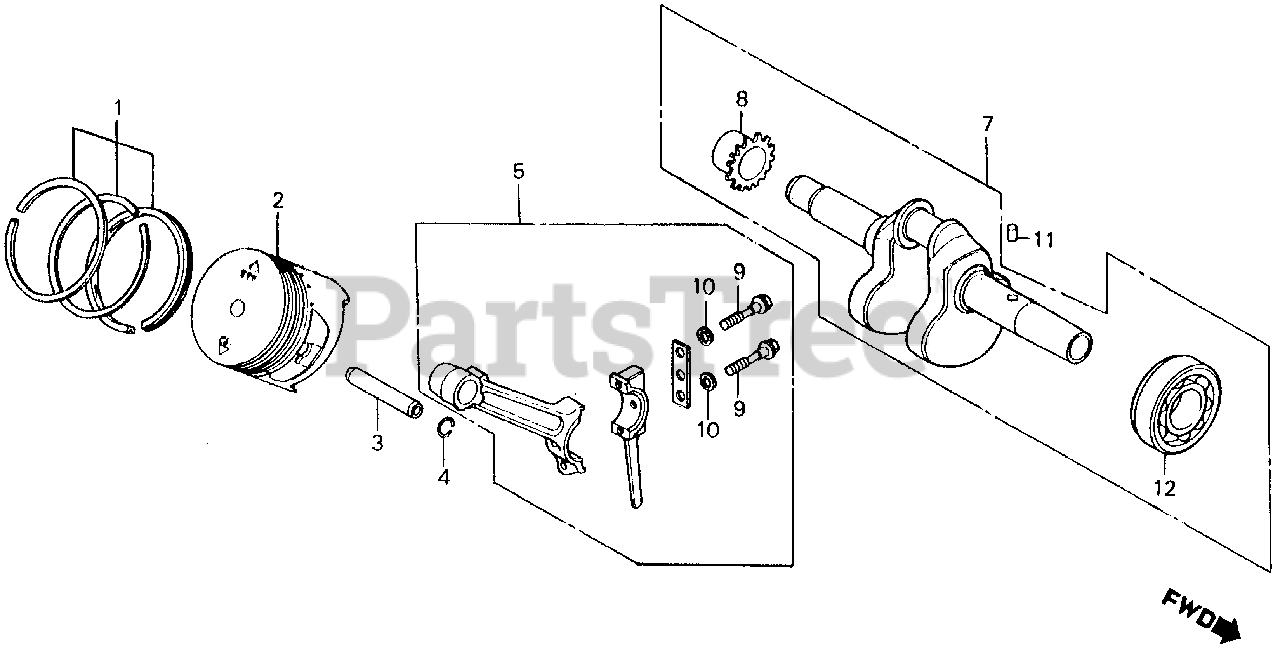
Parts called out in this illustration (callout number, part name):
1	RING SET, PISTON (STD)
1	RING SET, PISTON (OS 0.25)
1	RING SET, PISTON (OS 0.50)
1	RING SET, PISTON (0.75) (NOT AVAILABLE)
2	PISTON
2	PISTON (STD)
2	PISTON (OS 0.25)
2	PISTON (OS 0.50)
2	PISTON (0.75)
3	PIN, PISTON
4	CLIP, PISTON PIN (10MM)
5	ROD ASSY., CONNECTING (STD)
5	ROD ASSY., CONNECTING
7	CRANKSHAFT (NOT AVAILABLE)
8	SPROCKET, TIMING (NOT AVAILABLE)
9	BOLT, CONNECTING ROD
10	WASHER, LOCK
11	PIN, DOWEL (5X8)
12	BEARING, RADIAL BALL (6203)
